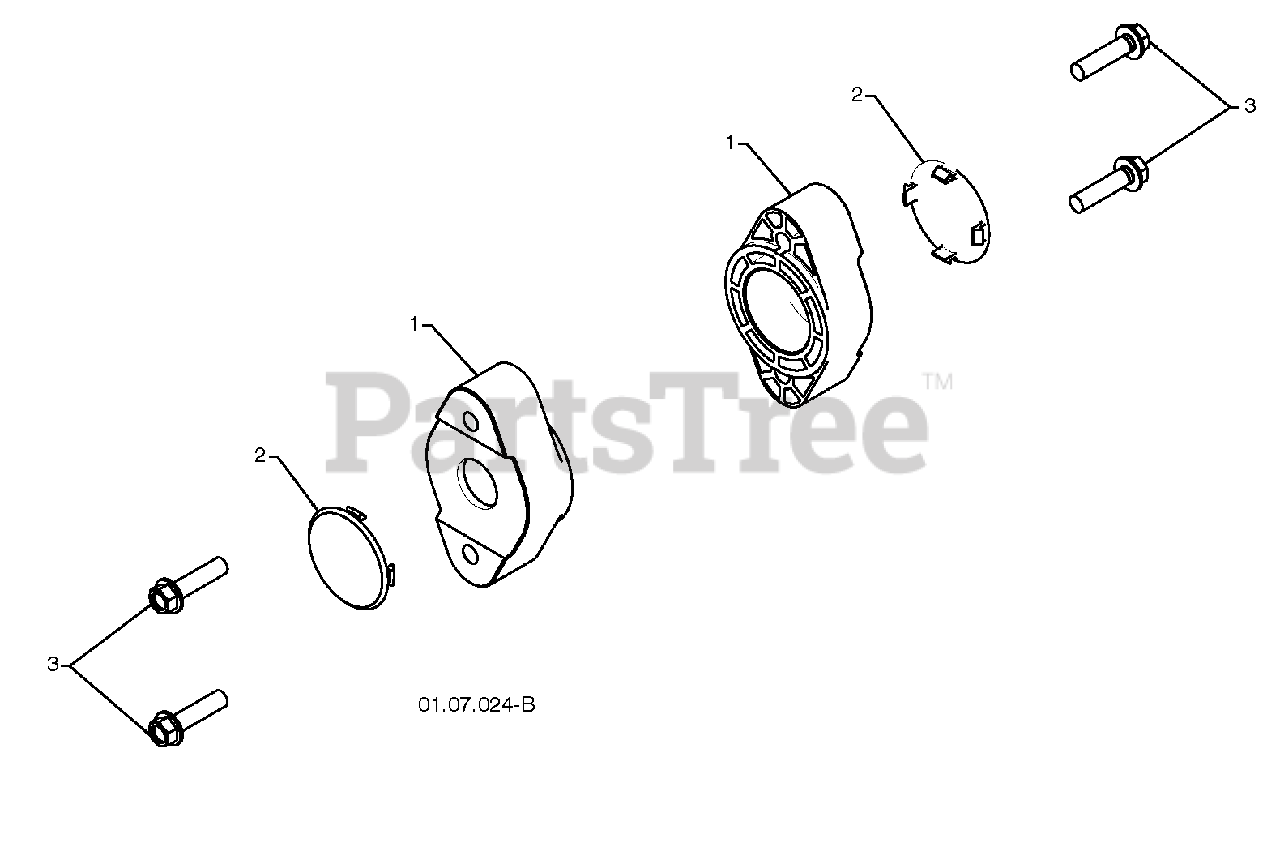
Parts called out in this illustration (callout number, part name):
1	AUGER BEARING
2	BEARING PLUG
3	SCREW 5/16-18 X 1.00
